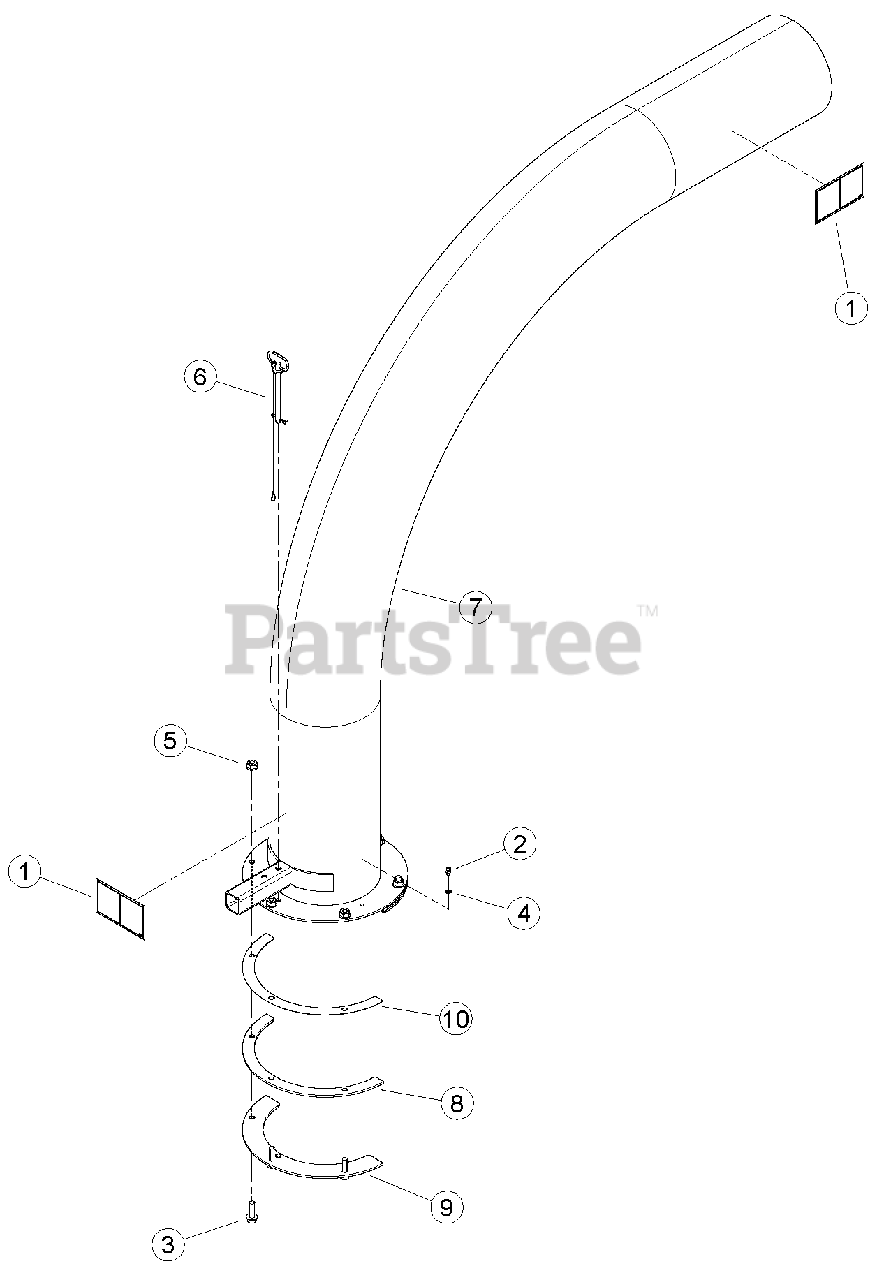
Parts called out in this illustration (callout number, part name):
1	DECAL, DISCHARGE ISO
2	FITTING, 1/4 SELF-TAP GREASE
3	BOLT, 3/8 X 1-1/4 FLANGE NC
4	WASHER, FLAT .254X.400X.048
5	NUT, 3/8-16 NYLOCK FLANGE
6	PIN, 3/8 X 4.25" DISCHARGE
7	WELDMENT, DL DISHCARGE TUBE
8	RING, DISCHARGE SPACER
9	RING, DISCHARGE CLAMP
10	SHIM, DISCHARGE SPACER RING
